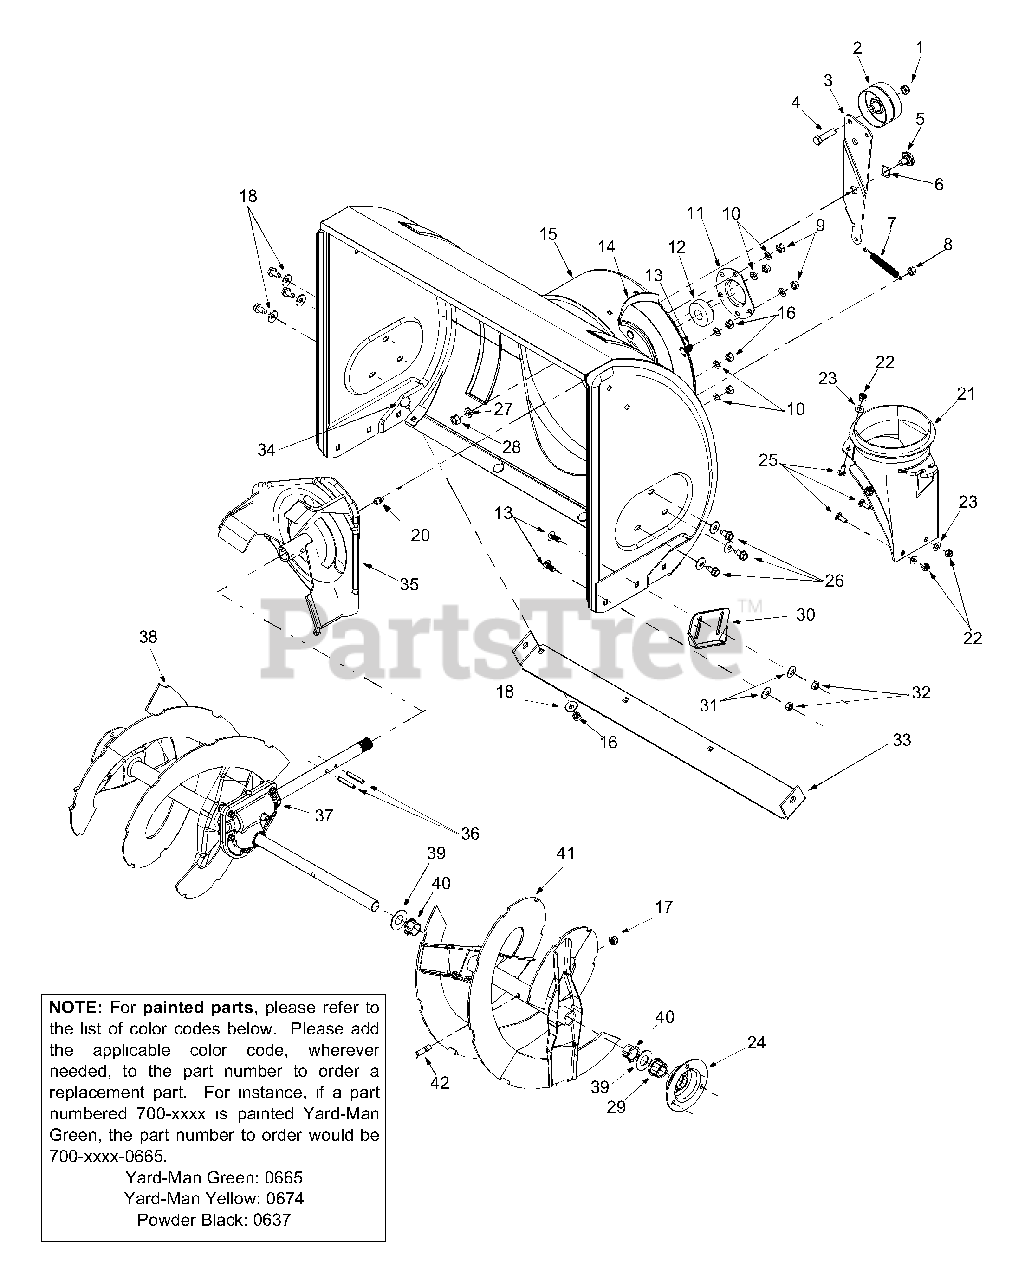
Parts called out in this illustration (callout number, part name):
1	Lock Jam Nut 3/8-24
2	Flat Idler
4	Hex Cap Screw 3/8-24 x 1.50
5	Shoulder Screw
6	Flat Washer
7	Extension Spring
8	Hex Nut 5/16-18
9	Carriage Bolt, 5/16-18 x 1.00
10	Lock Washer 5/16
11	Housing
12	Ball Bearing
13	Carriage Bolt, 5/16-18 x .75
17	Lock Nut 5/16-18
18	Belleville Washer
20	Grease Fitting
21	Chute Adapter
22	Hex Lock Nut 1/4-20
23	Flat Washer
24	Bearing Housing w/Fitting
25	Carriage Screw 1/4-20 x .75
26	Hex Screw 5/16-18
27	Lock Washer 3/8
28	Hex Nut 3/8-16
29	Hex Flange Bearing
31	Bell Washer
32	Hex Nut 5/16-18
34	Carriage Bolt 5/16-18 x .62
37	28" Gear Assy
39	Flat Washer
40	Flange Bushing
42	Shear Bolt 5/16-18 x 1.5
